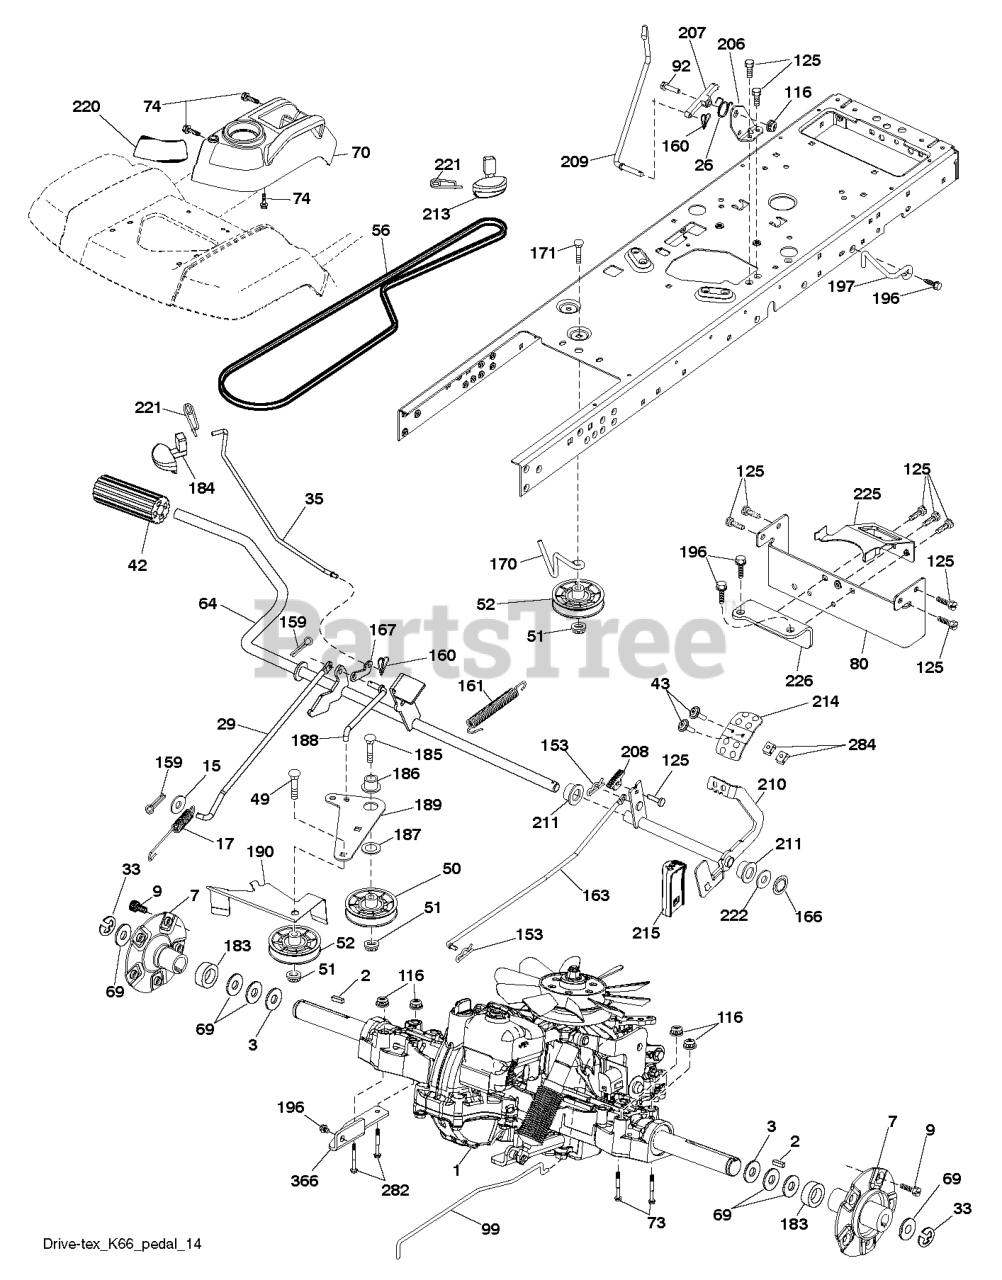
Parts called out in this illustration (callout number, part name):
2	KEY 1/4 X 2.5
7	HUB.ASM.WHEEL.REAR.23"TEX
9	HUB BOLT
15	WASHER
17	SPRING.BRAKE.K46
26	SPRING.RETURN.CRUISE
29	ROD.BRAKE.K66
33	E RING HYT
35	ROD .BRAKE. PARKING. GT. HUSQ.
42	PEDAL COVER T
43	SCREW.MACHINE.CR.1/4-20
50	IDLER.FLAT.910.OFFSET
51	NUT LOCK FLG 3/8-16 UNC
52	IDLER.V-GROOVE.910.OFFSET
64	SHAFT.ASM.PEDAL.BRK.CNTR
70	CONSOLE.ASM.RH.GT.FC.HUSQ
73	BOLT HEX 5/16-18 GR 5
74	SCREW.HI-LO.CONSOLE
80	TORQUE.STRAP.PNT.BLACK
92	BOLT
99	ROD.SPRING.BYPASS.K66.GT.Z
116	NUT LOCK HEX FLANGE 5/16-18
125	SCREW
153	RETAINER M
159	COTTER PIN
160	RETAINER CLIP
161	SPRING, RETURN LT
163	ROD.PEDAL.CONTROL
166	NUT.PUSH.625
167	LATCH.BRAKE.SPRING
170	KEEPER.V-IDLER.CENTER.
171	BOLT
183	SPACER.AXLE.HG.TEX
184	RB HANDLE.PARKG.BRK.HUS/PRED
186	SPACER.RETAINER
187	WASHER 12/32X2X10GA
188	RP.LINK.CLUTCH.GROUND.DRIVE
189	BELLCRANK.GROUND.DRIVE.TEX.
190	KEEPER.BELLCRANK.DRIVE
196	SCREW 3/8-16X1
197	BRKT.ANIT-ROTATION.CLUTCH
206	BRACKET.MOUNT.CRUISE.LATCH
207	LATCH.CONTROL.CRUISE
208	GEAR.SECTOR.CONTROL.CR
209	ROD.CONTROL.CRUISE.GT.
210	ROCKER.ASM.PEDAL.CONTR
211	BEARING.NYLON
213	KNOB.CONTROL.CRUSIE.HU
214	PEDAL.FORWARD.HUSQVARNA.DEALER
215	PEDAL.REVERSE.TEX.GT.4
220	REFLECTOR.RH.TEX GT
221	RETAINER.SPRING.CLIP.H
222	WASHER 21/32 X 1-1/4 X 10 GA.
225	KEEPER.BELT.TRANSAXLE.K66
226	BRACKET.MOUNT.TORQUE.K66.TG
282	BOLT HEX FLGHD 5/16-18X3 GR. 5
284	NUT.U-CHNL.1/4-20.550DP.350PNL
366	BRACKET.REINFORCEMENT
